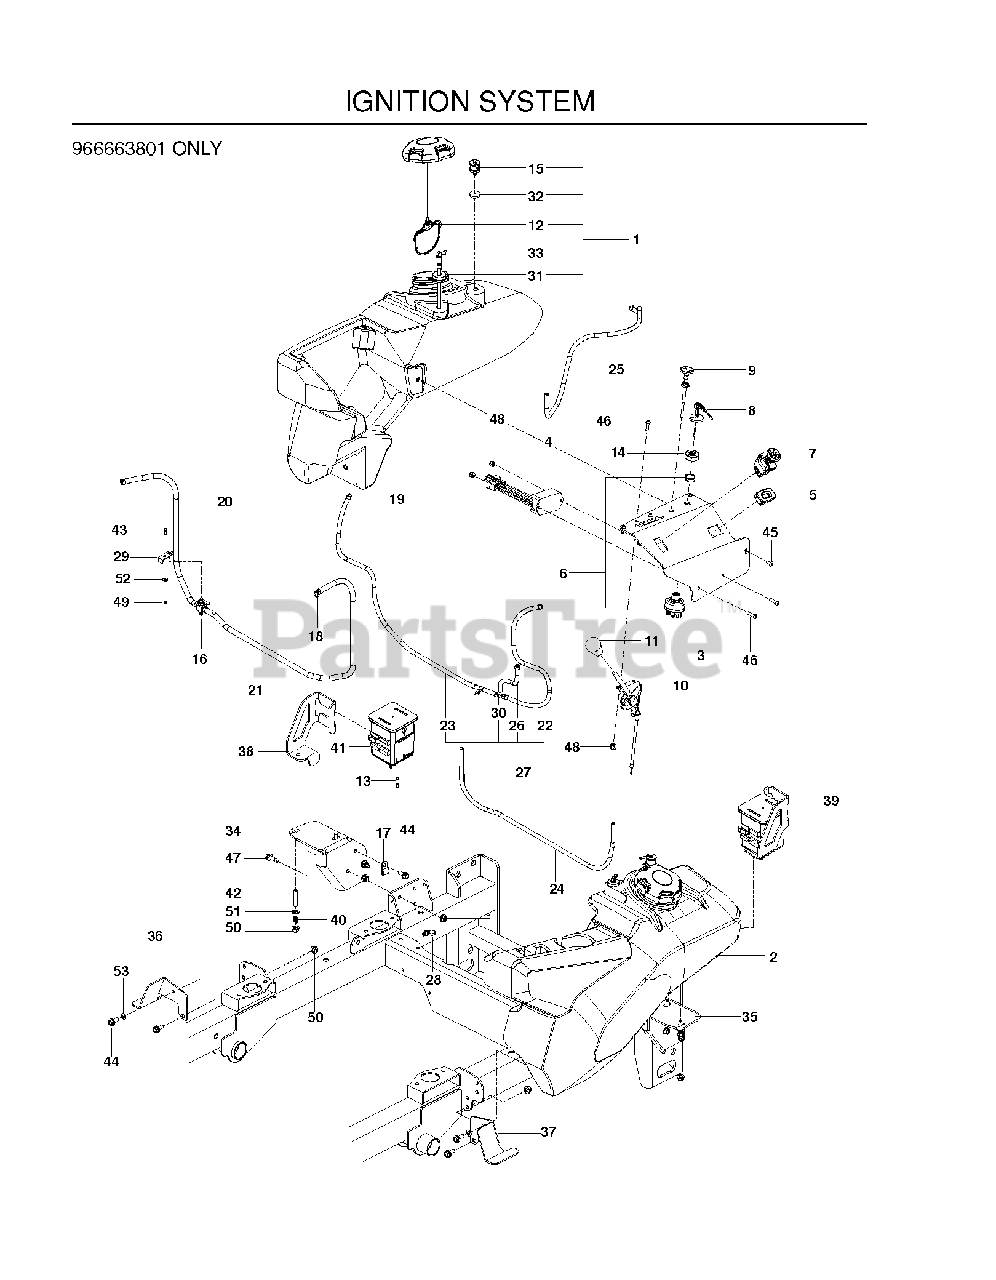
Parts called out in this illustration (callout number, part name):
1	RT FUEL TANK ASM EPA
2	LT FUEL TANK ASM EPA
3	PANEL.CONTROL.GAS.GRAY
4	TIMER, SEAT
5	HOUR METER
6	SWITCH, IGNITION, INDAK
7	SWITCH, PTO 10 AMP
8	KEY, IGNITION
9	CABLE, CHOKE, 48"
10	CABLE, THROTTLE, 46"
11	KNOB - SHIFT
12	CAP, FUEL
13	CAP, VINYL
14	CAP IGNITION NUT
15	VALVE.FUEL.CHECK
16	FUEL VALVE
17	DOUBLE TUBE CLAMP
18	HOSE CLAMP
19	CLAMP, HOSE
20	LINE, FUEL, 22"
21	LINE, FUEL, 38"
22	HOSE, 3/16" VAPOR, 21"
23	HOSE, VAPOR 3/16 X 39"
24	HOSE, VAPOR 3/16 X 30"
25	FUEL LINE 33"
26	HOSE, 3/16" VAPOR, 7-1/2"
27	ASSEMBLY, VAPOR LINE
28	TIE WRAP, 8-3/8", W/CLIP
29	BRACKET,FUEL VALVE, BLACK
30	TEE, FUEL LINE 3/16"
31	RUBBER GROMMET
32	GROMMET, CHECK VALVE
33	FITTING, FUEL
34	MOUNT, RT TANK, BLK
35	MOUNT, LT TANK, BLK
36	MOUNT, TANK, RT-BLK
37	MOUNT, TANK, LT-BLK
38	MOUNT, CANISATER, RT
39	MOUNT, CANISTER, LT
41	CANNISTER, CARBON
42	STUD, 5/16C
43	HCS 1/4C X 3/4 HCS
44	HHFS 5/16-18 X 3/4
45	SCR #10-24 X 3/8 SKT HD BLK OX
46	SCR #10-24 X .75 SKT HD BLK
47	RP BLT 5/16-18 X 1 THRD FORM D
48	NUT 10-24 NYLOC
49	JAM NUT 1/4C (2 2 PW01)
50	5/16-18 NYLOC FLANGE NUT
51	FLAT WASHER 5/16 SAE
52	WASHER 1/4 FLAT
53	WASH 5/16 DISC SPRING ZD
